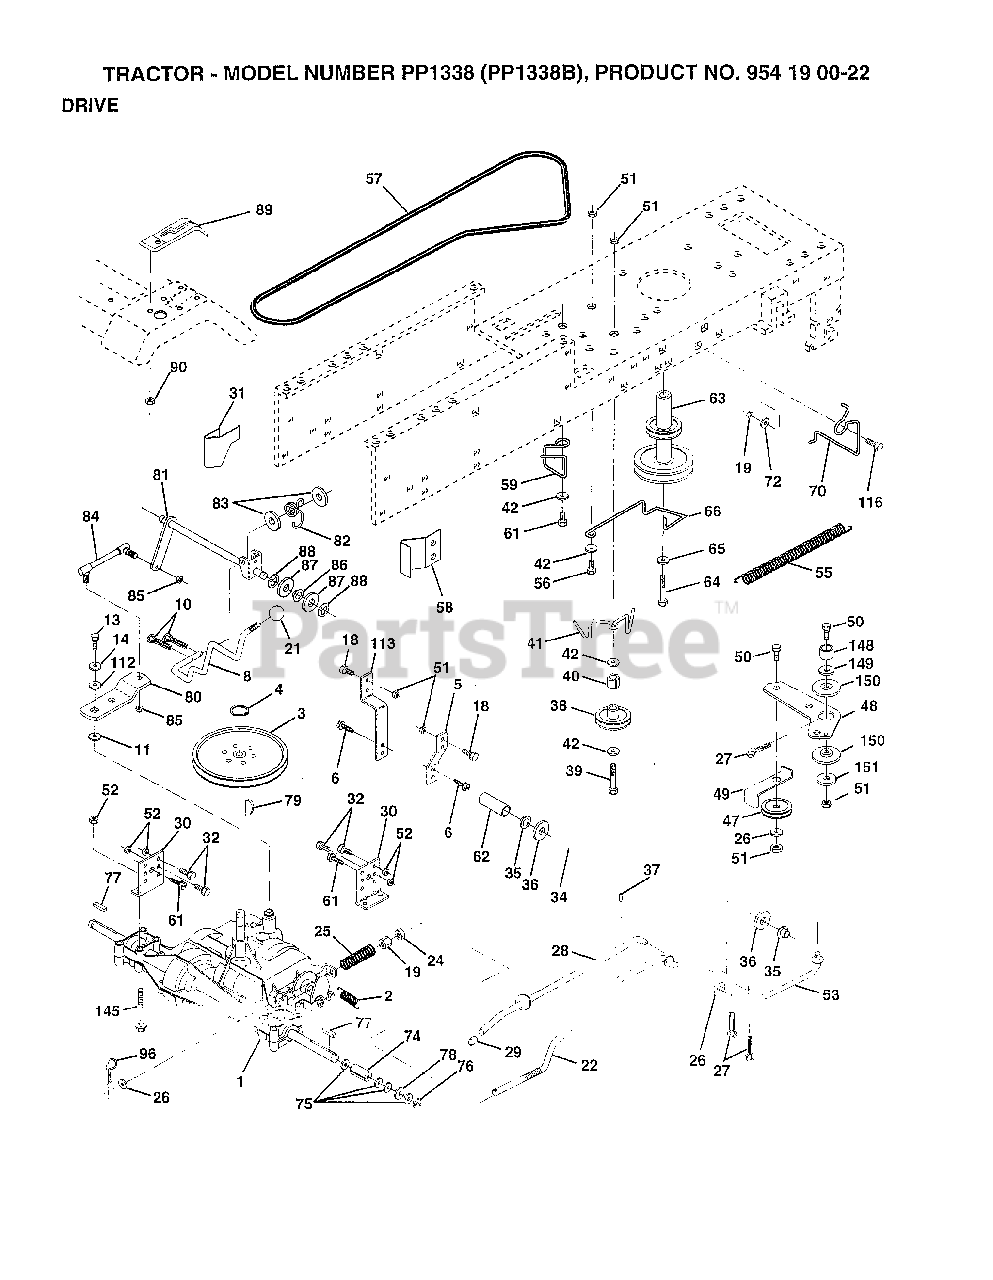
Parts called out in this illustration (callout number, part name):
2	SPRING.BRAKE.RETU
3	PULLEY TRANS
5	STRAP TORQUE
6	SCREW
8	ROD SHIFT FEND LT
10	PIN COTTER 1/8
11	WASH-SHFT PLT LT
13	BOLT.1/4-28.W/PAT
14	LOCKWASHER
18	BOLT
19	NUT
21	KNOB T (1/2-HOLE)
22	BRAKE ROD
24	NUT
25	SPRING ROD LT
26	WASHER
27	COTTER PIN
28	ROD.BRAKE.PARK.LT
29	PLUNGER CAP T
30	TRANSAXLE MTG BKT
31	"KEEPER,BELT LH T"
32	BOLT
34	SHAFT ASM-PEDAL F
35	NYLON BEARING
36	WASHER LT
38	IDLER, FLAT
39	BOLT
40	SPACER T
42	WASHER
48	BELLCRANK.CLUTCH
49	RETAIN BELT
53	"LINK, CLUTCH T"
55	"SPRING, RETURN LT"
58	"KEEPER,BELT RH T"
59	KEEPER BELT CNTSP
61	SCREW
62	PEDAL COVER T
63	PULLEY.ENGINE
64	BOLT
65	LOCKWASHER
66	KEEPER-BELT
70	KEEPER BELT ENG
72	WASHER
74	SPACER AXLE
76	E-RING LT
77	SQUARE KEY
78	WASHER
80	"ROD,LINK SHIFT"
81	SHAFT.CROSS
82	"SPRING,TORSION"
83	WASHER
84	"ROD,TIE "
85	NUT.CNT.LOCK.1/4
86	BUSHING
87	WASHER D
88	KLIP RING
90	NUT
112	WASHER LT
113	"STRAP,TORQUE"
116	BOLT RDHD 3/8-16
145	BOLT.HEX.FLGHD
149	SPACER RETAINER
150	BUSHING.NYLON
151	WASHER
